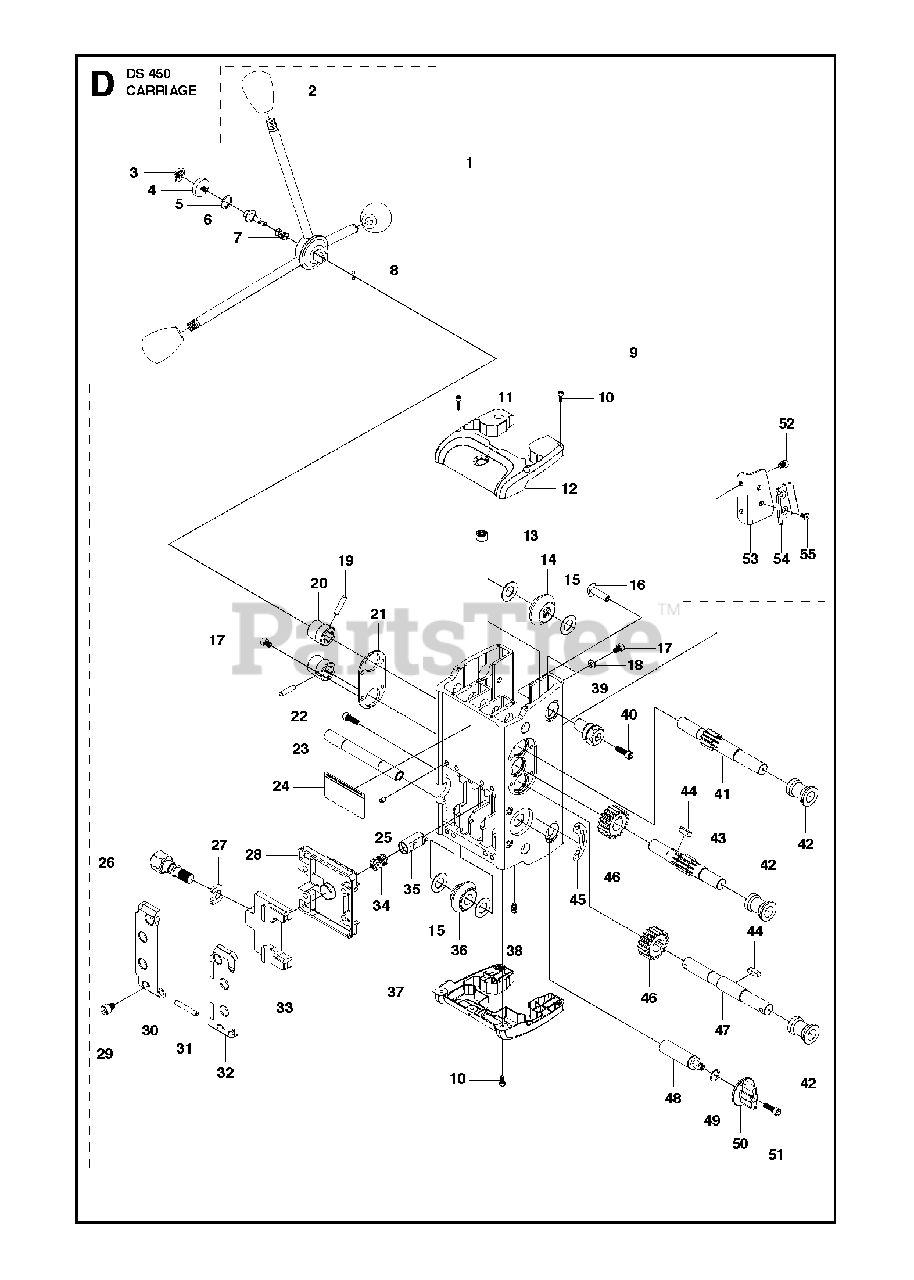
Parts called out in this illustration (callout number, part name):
15	RONDELLE BUTEE AS 1528/
19	PARALLEL PIN
22	SCREW IHSCM
25	PARALLEL PIN
40	SCREW IHSCM
